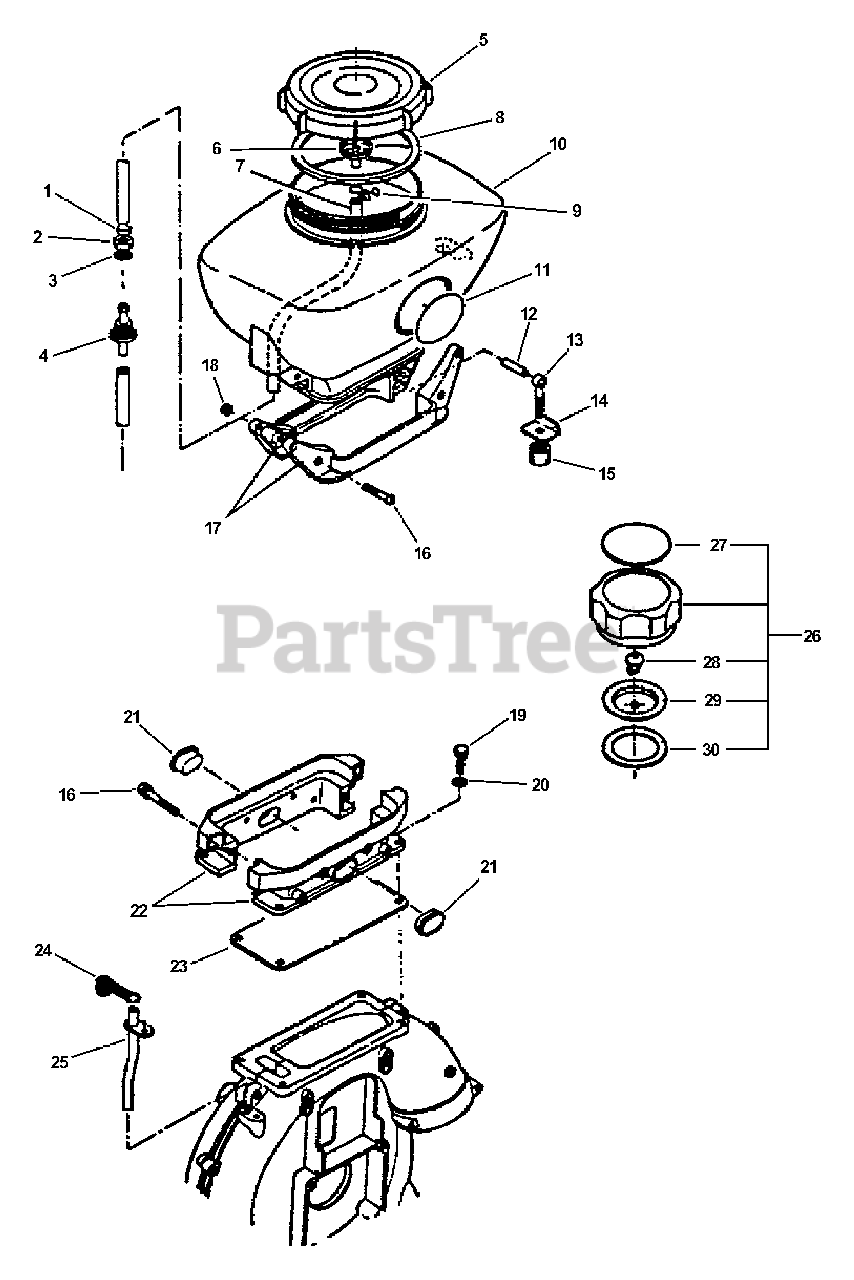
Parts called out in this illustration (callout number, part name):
1	CLAMP
3	WASHER 12×20×1
4	CONNECTOR, PIPE
5	CAP, CHEMICAL TANK
6	CONNECTOR, PIPE
7	PIPE, INNER PRESSURE 7×11×400BL
8	GASKET, CHEMICAL TANK
9	CLAMP
10	TANK, CHEMICAL
11	LABEL
16	SCREW 5×30
17	HOLDER
19	BOLT 6×20
22	CLAMP KIT
25	HOSE, AIR
26	CAP ASSY
27	LABEL - FUEL MIX
28	VALVE, CHECK
29	HOLDER, VENT
30	GASKET
